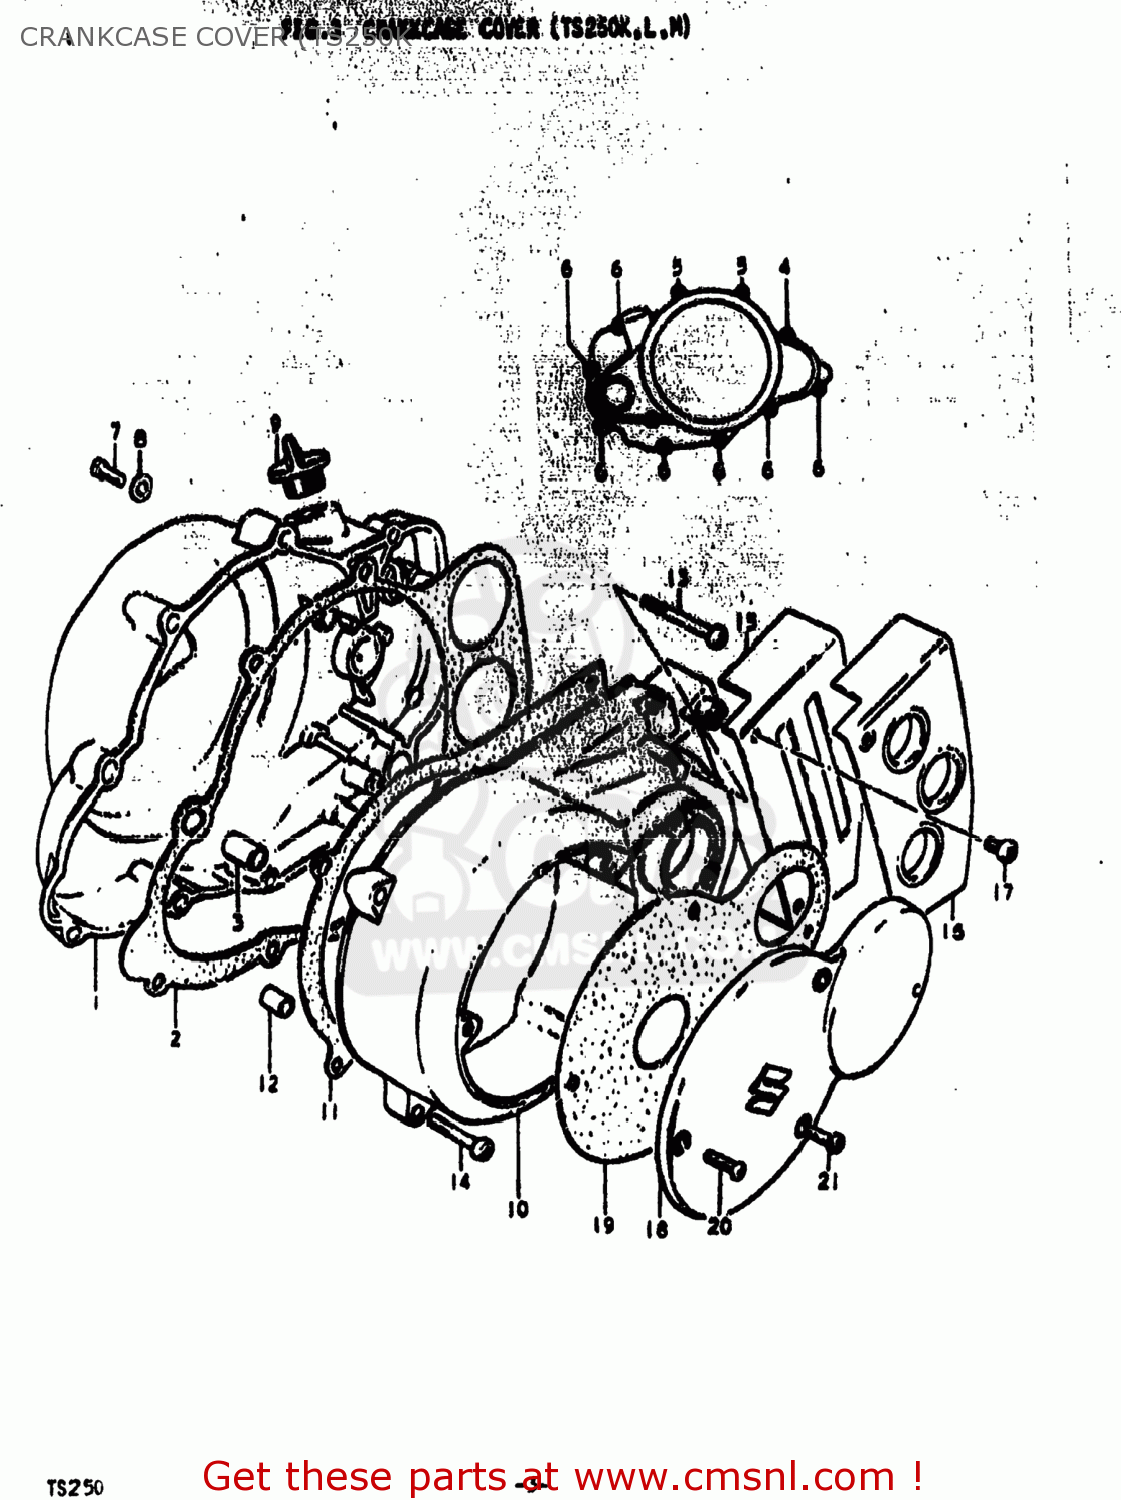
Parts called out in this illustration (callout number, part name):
1	COVER,CLUTCH
2	GASKET,CLUTCH COVER (MCA)
3	PIN
4	SCREW (6X45)
5	SCREW (6X35)
6	SCREW
7	SCREW(6X10)
8	GASKET(6.2X11X1) (NAS)
9	PLUG
10	COVER
11	GASKET,MAGNETO COVER (NAS)
12	PIN
13	SCREW
14	SCREW
15	COVER,SPROCKET
16	COVER,SPROCKET
17	SCREW
18	CAP,MAGNETO INSPECTION
19	GASKET,MAGNETO INSPECTION (NAS)
20	SCREW
21	SCREW
